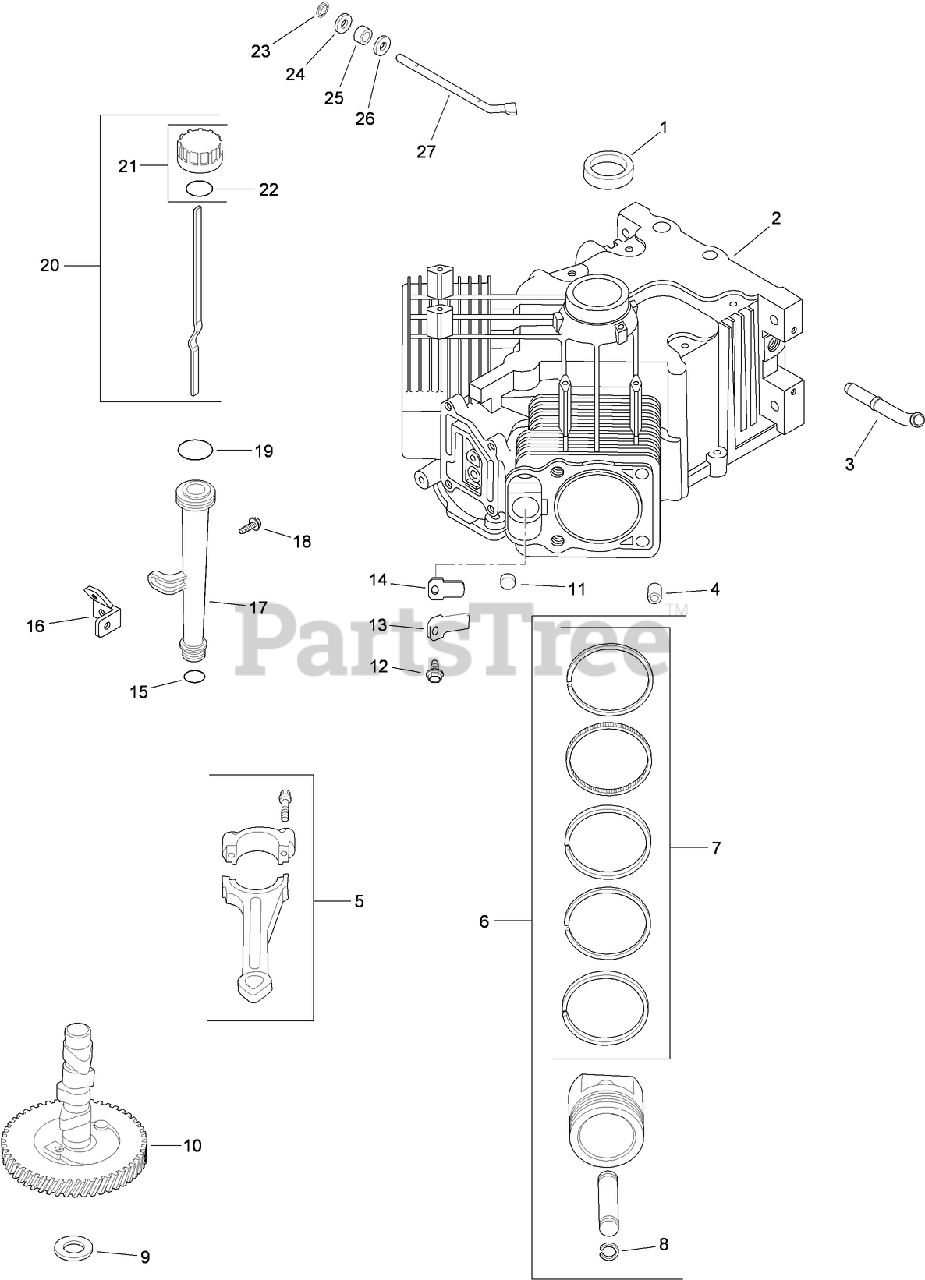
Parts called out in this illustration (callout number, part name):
1	SEAL-OIL (HELIX LIP)
2	CV23-674 MINI BLOCK
3	Fitting
4	PIN-LOCATING
5	ROD-CONNECTING (STD)
5	ROD-CONNECTING (.25)
6	PISTON W/RING SET (STD, 80mm) (INCLUDES 7, 8)
6	PISTON W/RING SET (.08)
6	PISTON W/RING SET (.25)
6	PISTON W/RING SET (.50)
7	PISTON RING SET (STD)
7	PISTON RING SET (.08)
7	PISTON RING SET (.25)
7	PISTON RING SET (.50)
8	RETAINER-PIN, PISTON
9	SHIM-CAMSHAFT (RED .032)
9	SHIM-CAMSHAFT (BLACK .04)
9	SHIM-CAMSHAFT (WHITE .028)
9	SHIM-CAMSHAFT (BLUE .03)
9	SHIM-CAMSHAFT (YELLOW .034)
9	SHIM-CAMSHAFT (GREEN .036)
9	SHIM-CAMSHAFT (GRAY .038)
10	Camshaft Kit
11	PLUG-CUP
12	SCREW-HHFTF (M5X.80X10)
13	RETAINER-REED, BREATHER
14	Reed-Breather
15	O-RING (LOWER OIL FILL TUBE)
16	BRACKET-TUBE, OIL FILL
17	OIL FILL TUBE ASM
18	SCREW-FLANGE, THREAD FORMING (M5X0.8X16)
19	O-RING (UPPER OIL FILL TUBE)
20	Dipstick ASM (INCLUDES 21, 22)
21	OIL FILL CAP KIT (YELLOW)
22	O-RING (DIPSTICK)
23	RETAINER-RING
24	WASHER-FLAT (9MM)
25	SEAL-CROSS SHAFT, GOVERNOR
26	WASHER-FLAT (11/32) (BOTTOM)
27	SHAFT-CROSS, GOVERNOR
